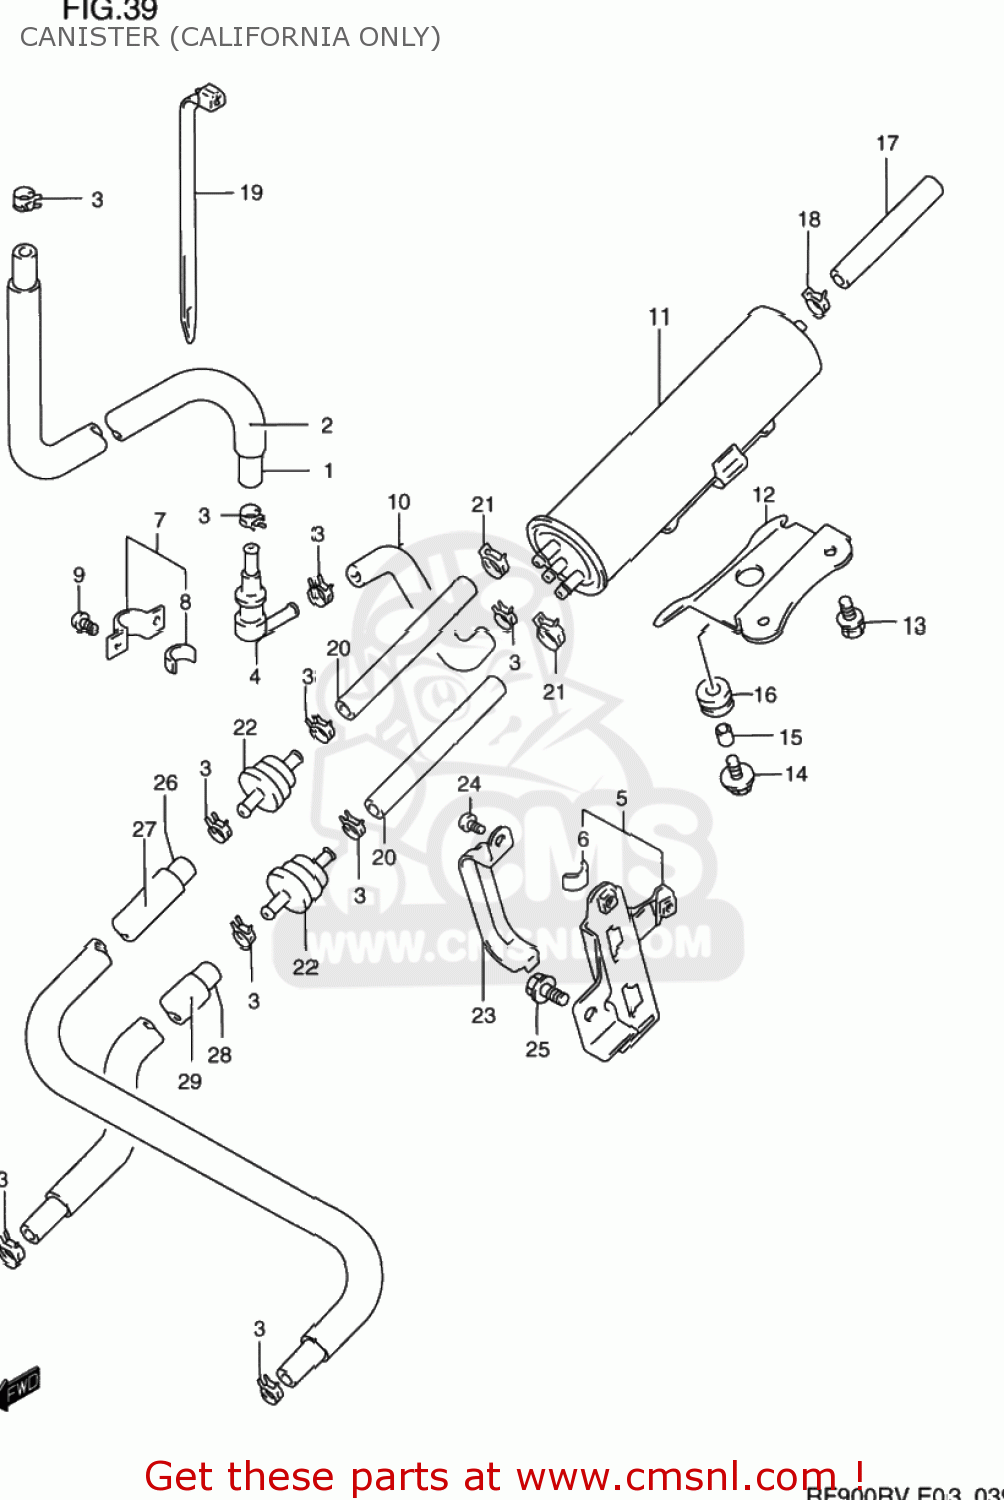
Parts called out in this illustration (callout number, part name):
1	HOSE(5.4X11.4X2000)
2	PROTECTOR(14.5X15.5X600)
3	CLIP
4	VALVE,FUEL TANK BREATHER
5	BRACKET,FUEL TANK BREATHER
6	CUSHION
7	PLATE,FUEL TANK BREATHER NO.2
8	CUSHION
9	SCREW
10	HOSE(5.4X11.4X600)
11	CANISTER ASSEMBLY,CHARCOAL
12	BRACKET,CANISTER
13	BOLT
14	BOLT
15	SPACER
16	CUSHION
17	HOSE(7X12X600)
18	CLIP
19	CLAMP(L:125)
20	HOSE(5.4X11.4X600)
21	CLIP
22	VALVE,CANISTER PURGE
23	HOLDER,CANISTER PURGE
24	SCREW
25	BOLT
26	HOSE(5.4X11.4X2000)
27	PROTECTOR,HOSE NO.1
28	HOSE(5.4X11.4X600)
29	PROTECTOR,HOSE NO.2
